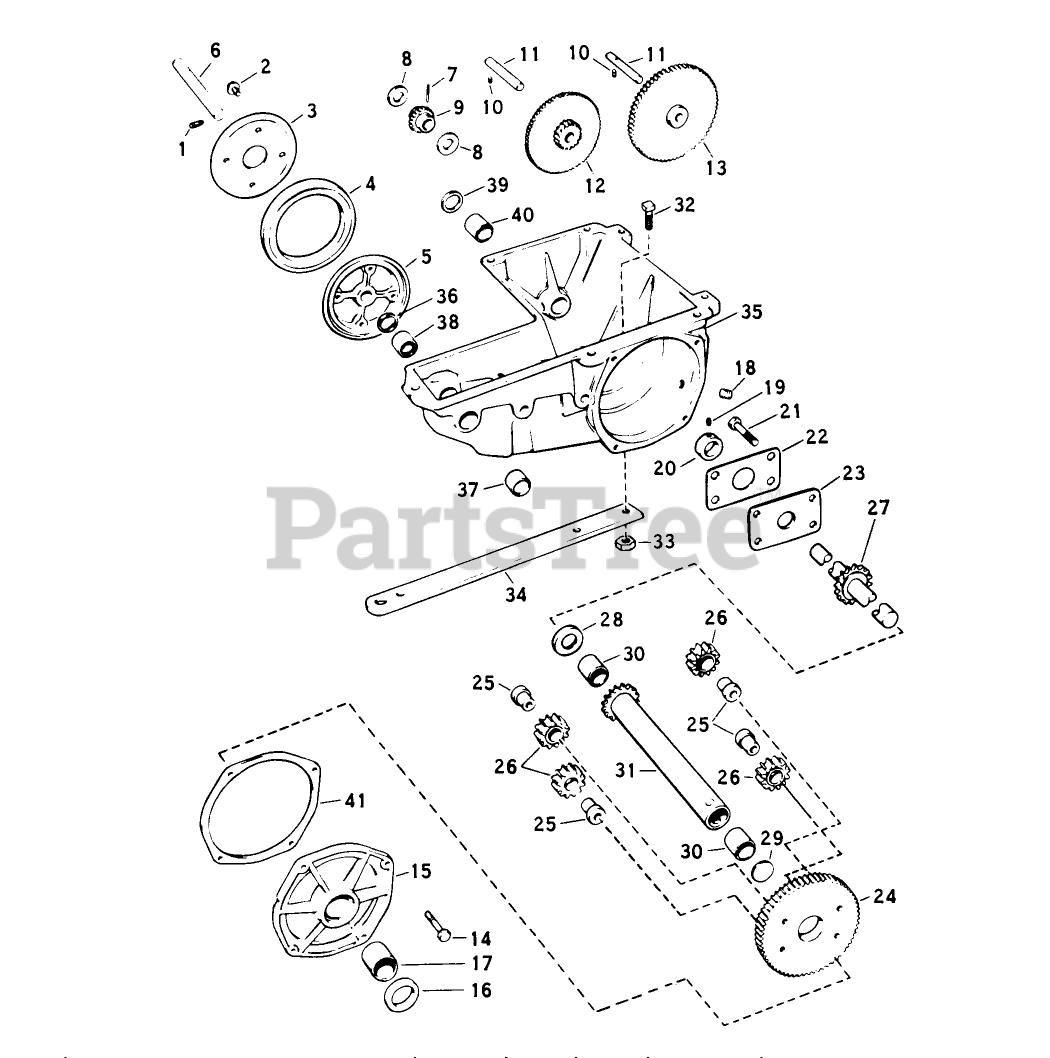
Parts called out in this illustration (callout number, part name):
10	SET SCREW
21	Screw-Differential
24	Gear-Reduction (No. 3)
26	Gear-Planet, Differential
34	Bar-Draw
